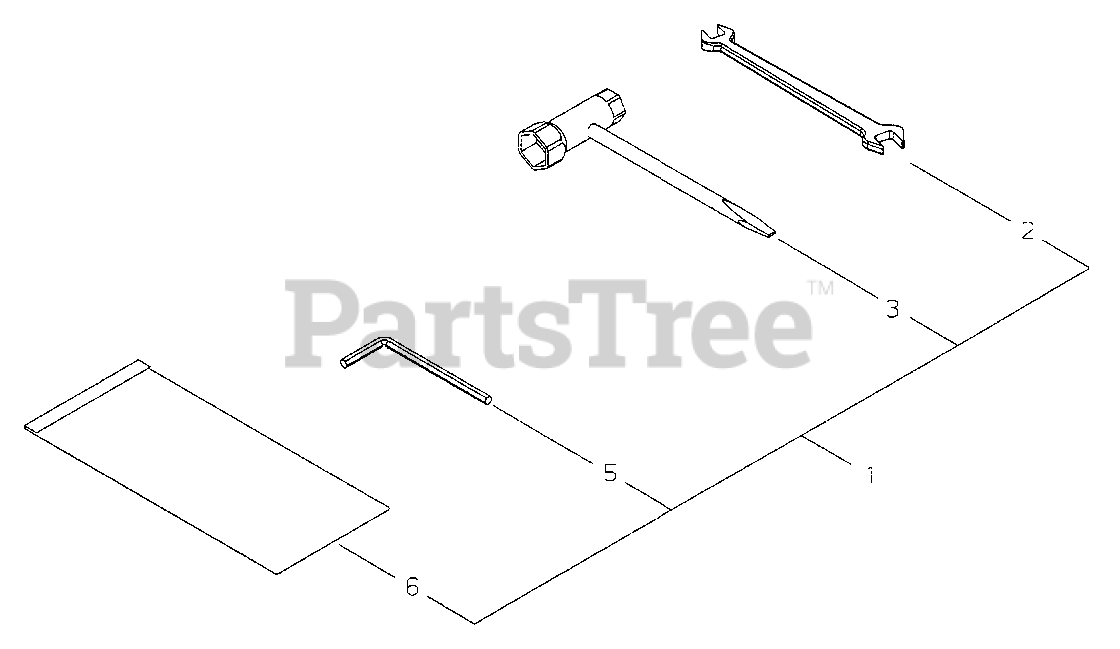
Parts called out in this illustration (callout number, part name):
1	TOOL KIT
2	SPANNER - 8X10mm
3	T-WRENCH - 13X16mm
4	HEX KEY - 4mm
5	BAG, TOOL
